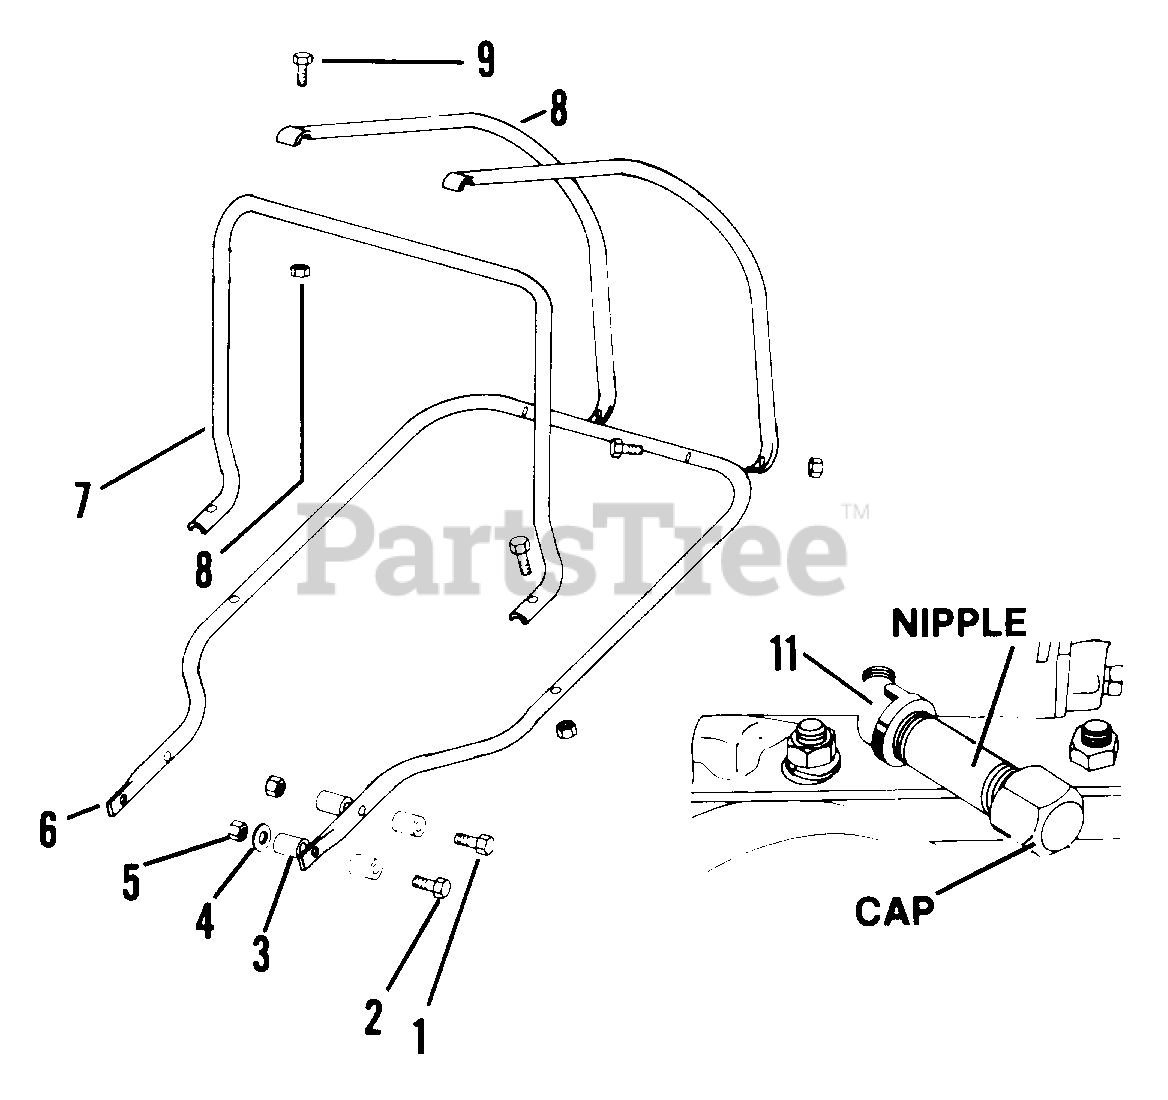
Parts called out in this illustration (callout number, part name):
1	BLT-HEX .38-16X1.75 PL GR2
2	BLT-HEX .38-16X2.50 PL GR2
3	SPACER .63 X .38 X .75
4	WSHR-FL-STL .390X.875X.18 PL
5	NUT-LK-CTR .375-16 GR A PL
6	MOUNTING TUBE
7	UPPER TUBE
8	NUT-LK .312-18 GR A PL
9	BLT-HEX .31-18X1.50 PL GR2
11	1/2 B I 45 DEGREE STREET ELBOW
11	1/4 B I 45 DEGREE STREET ELBOW
